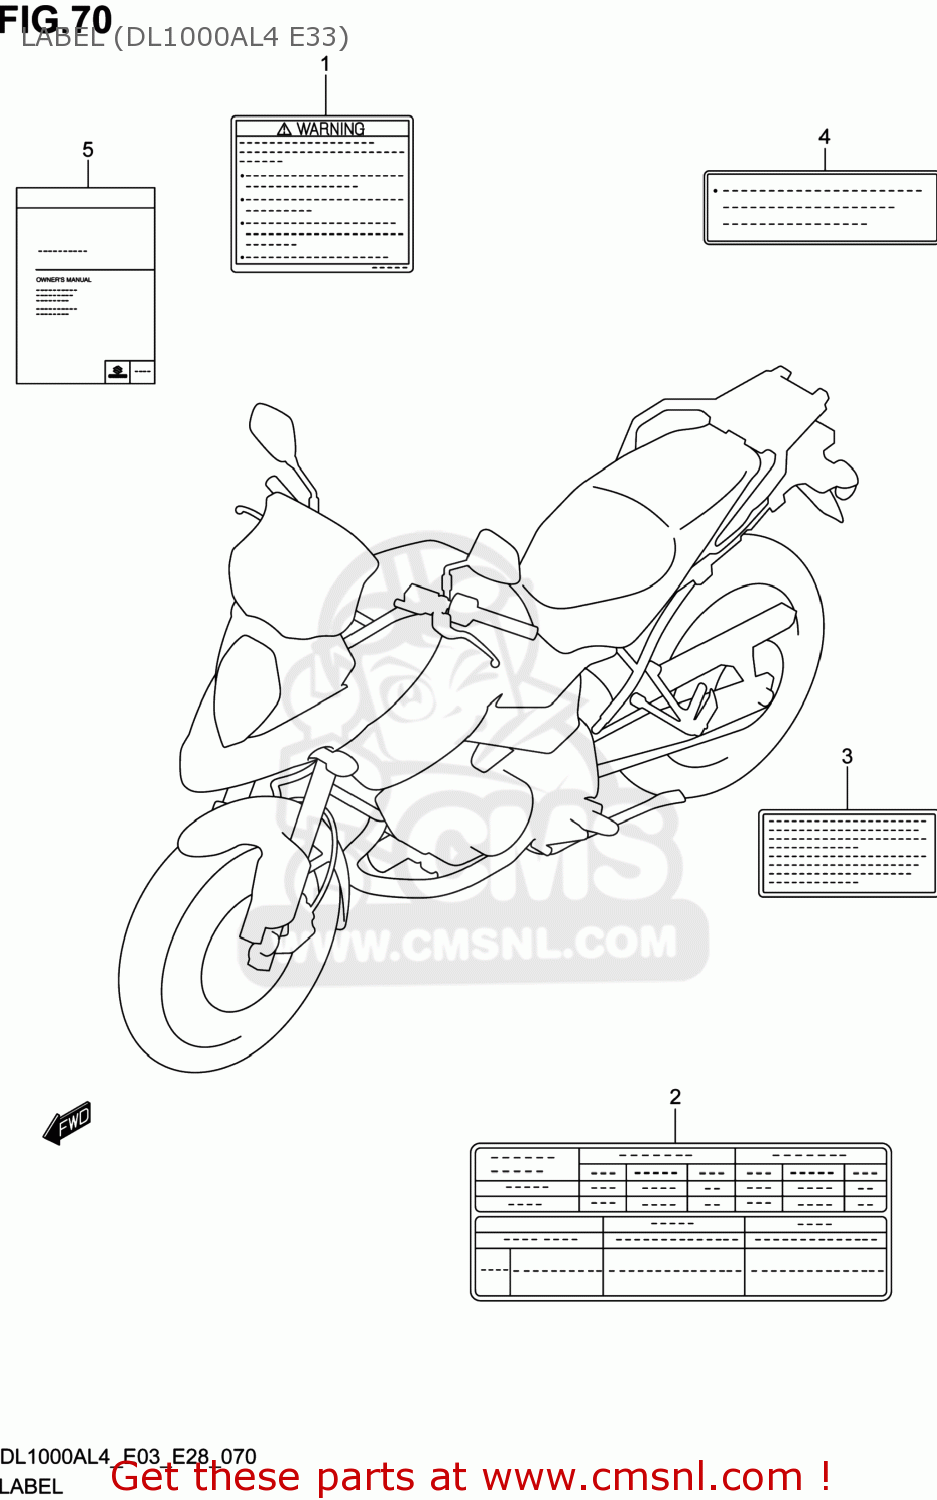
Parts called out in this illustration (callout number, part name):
1	LABEL,GENERAL WARNING
2	LABEL,TIRE INFORMATION
3	LABEL,MANUAL NOTICE
4	LABEL,FUEL INFORMATION
5	MANUAL,OWNER'S
